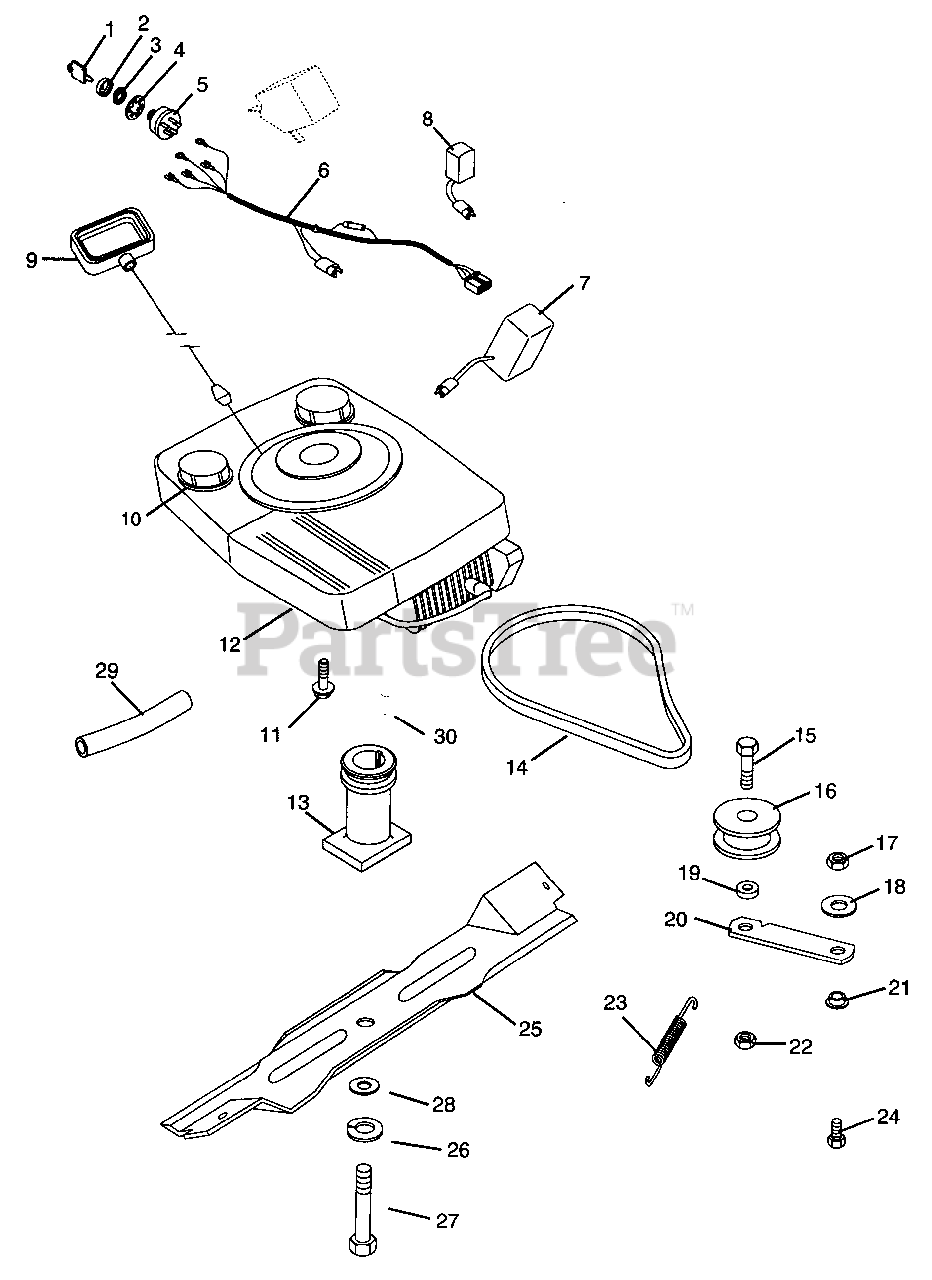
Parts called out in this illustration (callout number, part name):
1	KEY -W/CAP
2	CAP - IGNITION SWITCH
3	NUT-PANEL .625-32 GRECO
4	WSHR-LK-INT .625X.045 PL
5	KEY SWITCH
6	WIRE HARNESS
7	BATTERY,
8	BATTERY CHARGER
9	HANDLE, RECOIL START
10	FUEL CAP
11	SCR-TAP .375-16X1.0 HWH PL TR
12	ENG, 5 HP KAW (W/PRESS LUBE)
12	ENGINE TEC. 5.0HP. CENTURA
12	ENGINE TEC. 5.5HP. CENTURA
12	ENGINE B&S 5.5HP. DIAMOND PLUS
12	ENGINE B&S 5.5HP DMND PLS 8195
12	ENGINE TEC 6HP REC VECTOR 8195
12	ENGINE TEC 6HP ELE VECTOR 8195
12	ENGINE B/S 5HP QUANTUM XTE
12	ENGINE TEC. 5HP RECOIL 2 CYCLE
12	ENGINE TEC 5.0HP CENTURA CARB
12	ENGINE TEC 5.5HP CENTURA CARB
12	ENGINE ROBIN 6HP. PR LUBE.
12	ENGINE B/S 5HP. REC QUAN. I/C
13	PLZ READ SERVICE LETTER #L-429
13	BLADE ADAPTER
13	BLADE ADAPTER 1.00 DIA SPLINE
14	V-BELT, 3L-COGGED
15	BLT-HEX .44-14X1.25 PL GR2
16	IDLER-FLAT 1.75 X .47
17	NUT-LK .312-18 GR A PL
18	WSHR-FL-STL .323X.625X.062 PL
19	SPACER .52 X .45 X .34
20	IDLER ARM
21	BSHG-FLG .325X.501X.250X1.120
22	NUT-LK .437-14 GR A PL
23	SG-TENS .043X.44X3.31 WLD 5.8
24	BLT-HEX .31-18X.75 PL GR2
25	21" MOWER BLADE
25	21IN MULCHING BLADE
26	WSHR-LK .375X.094 MED PL
27	BLT-HEX .38-24X2.00 PL GR5
28	WSHR-HDND-THR .390X1.50X.125PL
29	DRAIN HOSE
30	KEY-WDRF .156X.625X.25 SAE 6
